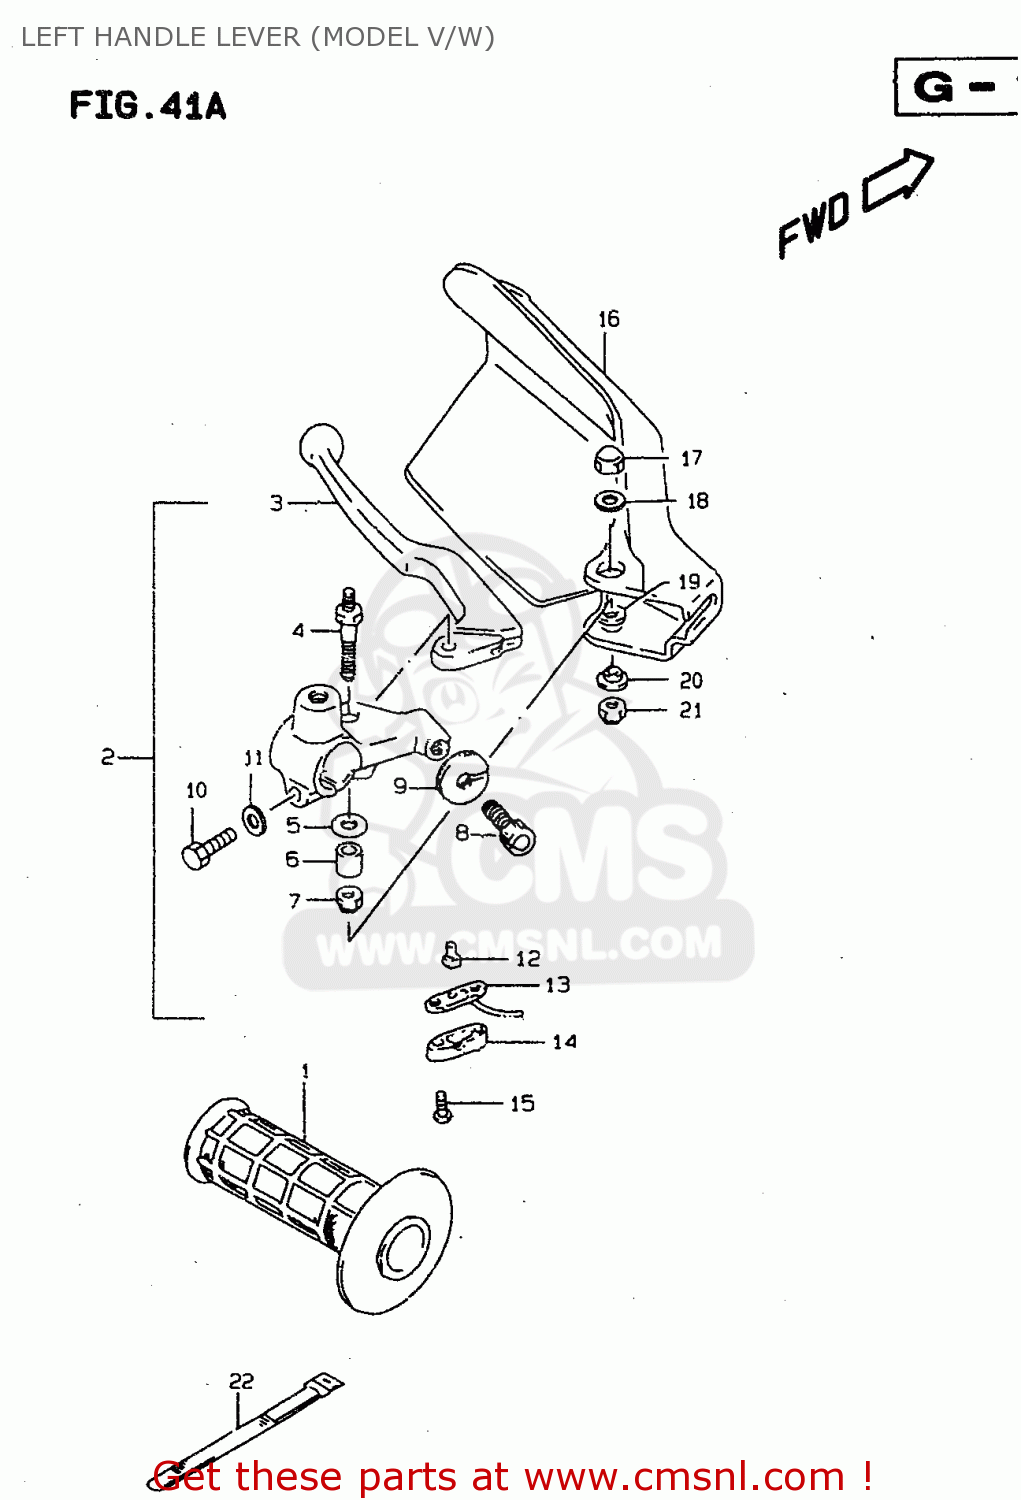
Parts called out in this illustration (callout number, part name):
1	GRIP,L
2	LEVER ASSY,CLUTCH
3	LEVER,CLUTCH
4	BOLT,CLUTCH LEVER PIVOT
5	WASHER
6	SPACER,LEVER SET
7	NUT
8	ADJUSTER,CABLE
9	NUT,LOCK
10	BOLT
11	WASHER
12	CONTACT,SWITCH
13	HARNESS ASSY,WIRE
14	COVER,FR BK TERMINAL BASE
15	SCREW
16	COVER,KNUCKLE,LEFT
17	NUT
18	WASHER(6.5X20X1.6)
19	WASHER(6.5X16X1.2)
20	WASHER
21	NUT 6MM
22	CLAMP(L:120)
